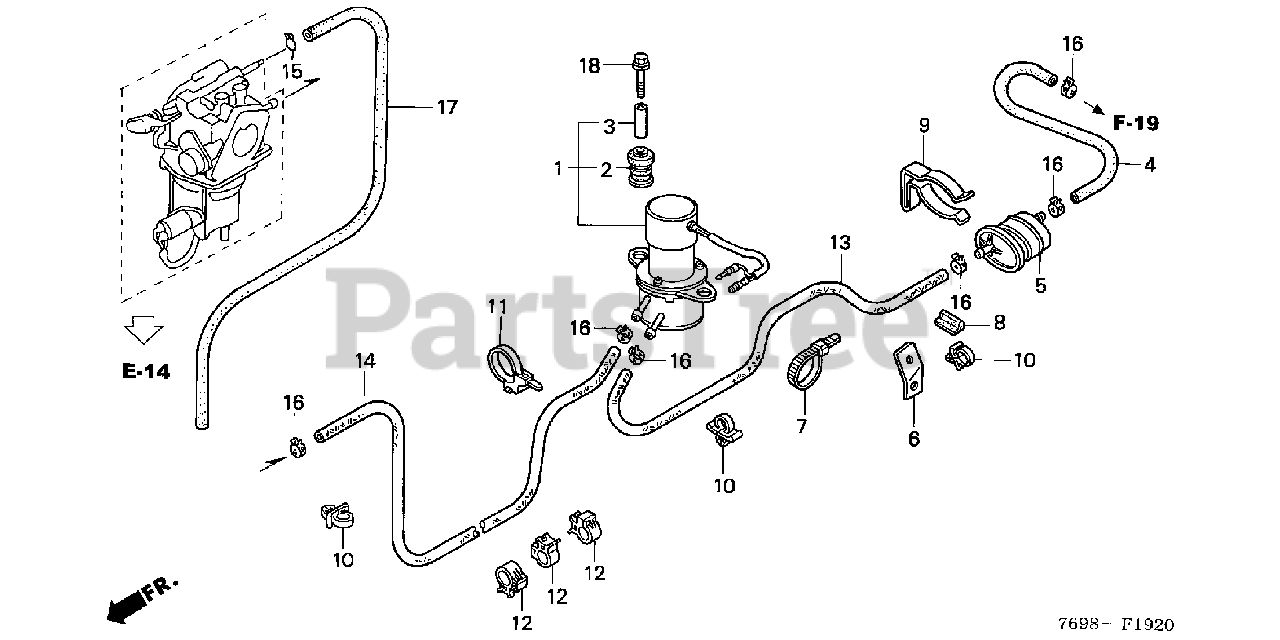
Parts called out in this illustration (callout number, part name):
1	PUMP ASSY., FUEL
2	RUBBER, FUEL PUMP SETTING
3	COLLAR, DISTANCE
4	TUBE, FUEL
5	FILTER, FUEL
6	PLATE, FUEL HOSE CLAMP
7	BAND B1, CABLE
8	SEAL A, COLUMN COVER (20MM)
9	CLAMP, FUEL STRAINER
10	CLIP, WIRE HARNESS
11	CLIP, HARNESS BAND (15)
12	CLIP, CABLE (15MM)
13	BULK HOSE, FUEL (5.5X8000) (5.5X430)
14	BULK HOSE, FUEL (5.5X8000) (5.5X860)
15	CLIP, TUBE (B7)
16	CLIP, TUBE (D10.5)
17	BULK HOSE, VACUUM (3.5X1000) (3.5X410)
18	BOLT, FLANGE (6X32)
